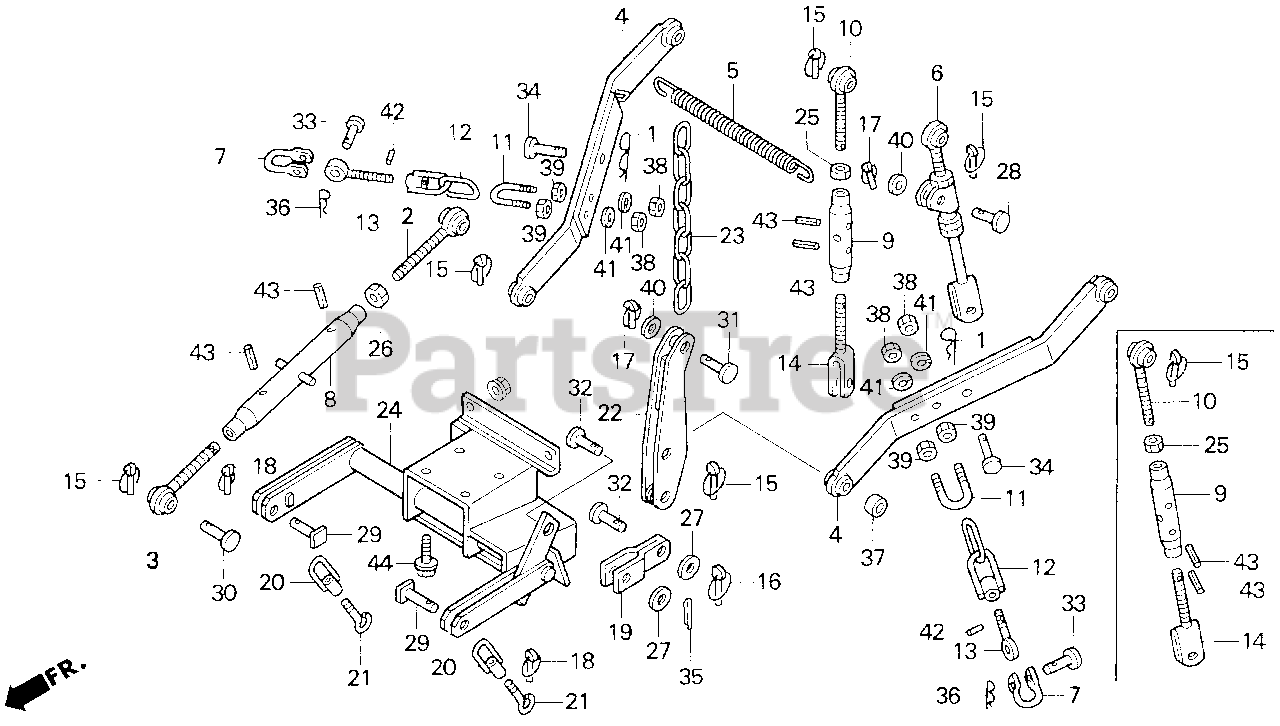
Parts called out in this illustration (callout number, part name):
9	BUCKLE, LIFT ROD TURN (NOT AVAILABLE)
10	ROD, LIFT (UPPER) (NOT AVAILABLE)
14	ROD, R. LIFT (LOWER) (NOT AVAILABLE)
15	LINCHPIN (A) (NOT AVAILABLE)
17	LINCHPIN (B) (NOT AVAILABLE)
25	NUT, HEX. (3/4"-10) (NOT AVAILABLE)
31	PIN, LINK (5/8"X3) (NOT AVAILABLE)
40	WASHER, PLAIN (NOT AVAILABLE)
43	PIN, SPRING (3/16"X0.75") (NOT AVAILABLE)
